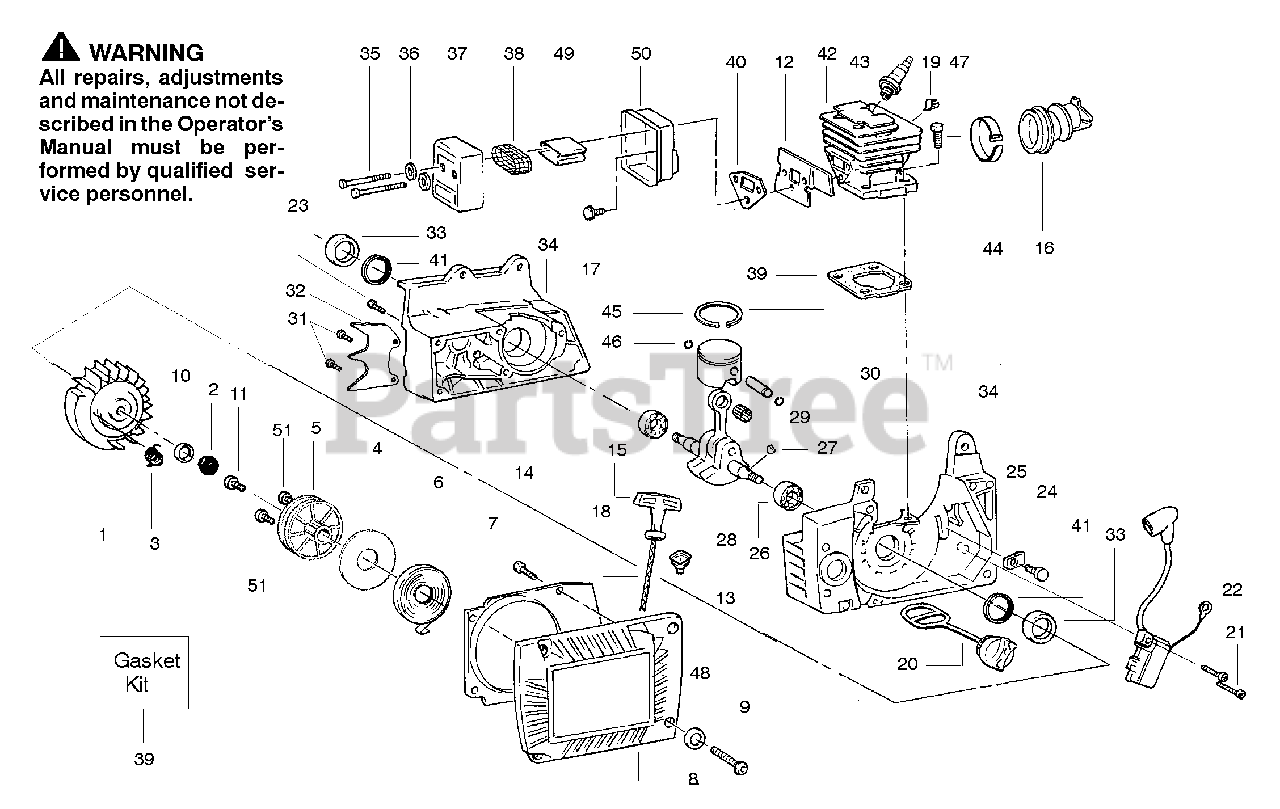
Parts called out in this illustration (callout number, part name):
1	Flywheel Ass'y.
2	Nut-Flywheel
3	Spring-Starter Dog
5	Starter Pulley
6	Starter Spring
7	Baffle Plate
8	Fan Housing Ass'y.
12	Muffler Back Plate T1
12	Muffler Back Plate T2
13	Eyelet Replacement Kit
15	Starter Handle
18	Rope Kit
20	Oil Cap Ass'y. (Incl. "O" Ring)
21	Screw
22	Ignition Module
26	Crankshaft Bearing
27	Flywheel Key
28	Connecting Rod Ass'y.
29	Piston Pin Bearing
30	Piston Kit
33	Crankshaft Seal
34	Crankcase Ass'y.
37	Muffler Cover T1
37	Muffler Cover T2
38	Spark Arrestor Screen
39	Gasket Kit
40	Muffler Gasket
41	Snap Ring
42	Cylinder Ass'y.
43	Spark Plug (RCJ-6Y)
44	Clamp Ass'y.
45	Piston Ring
46	Retainer
49	Muffler Body T1
49	Muffler Body T2
50	Muffler Diffuser
